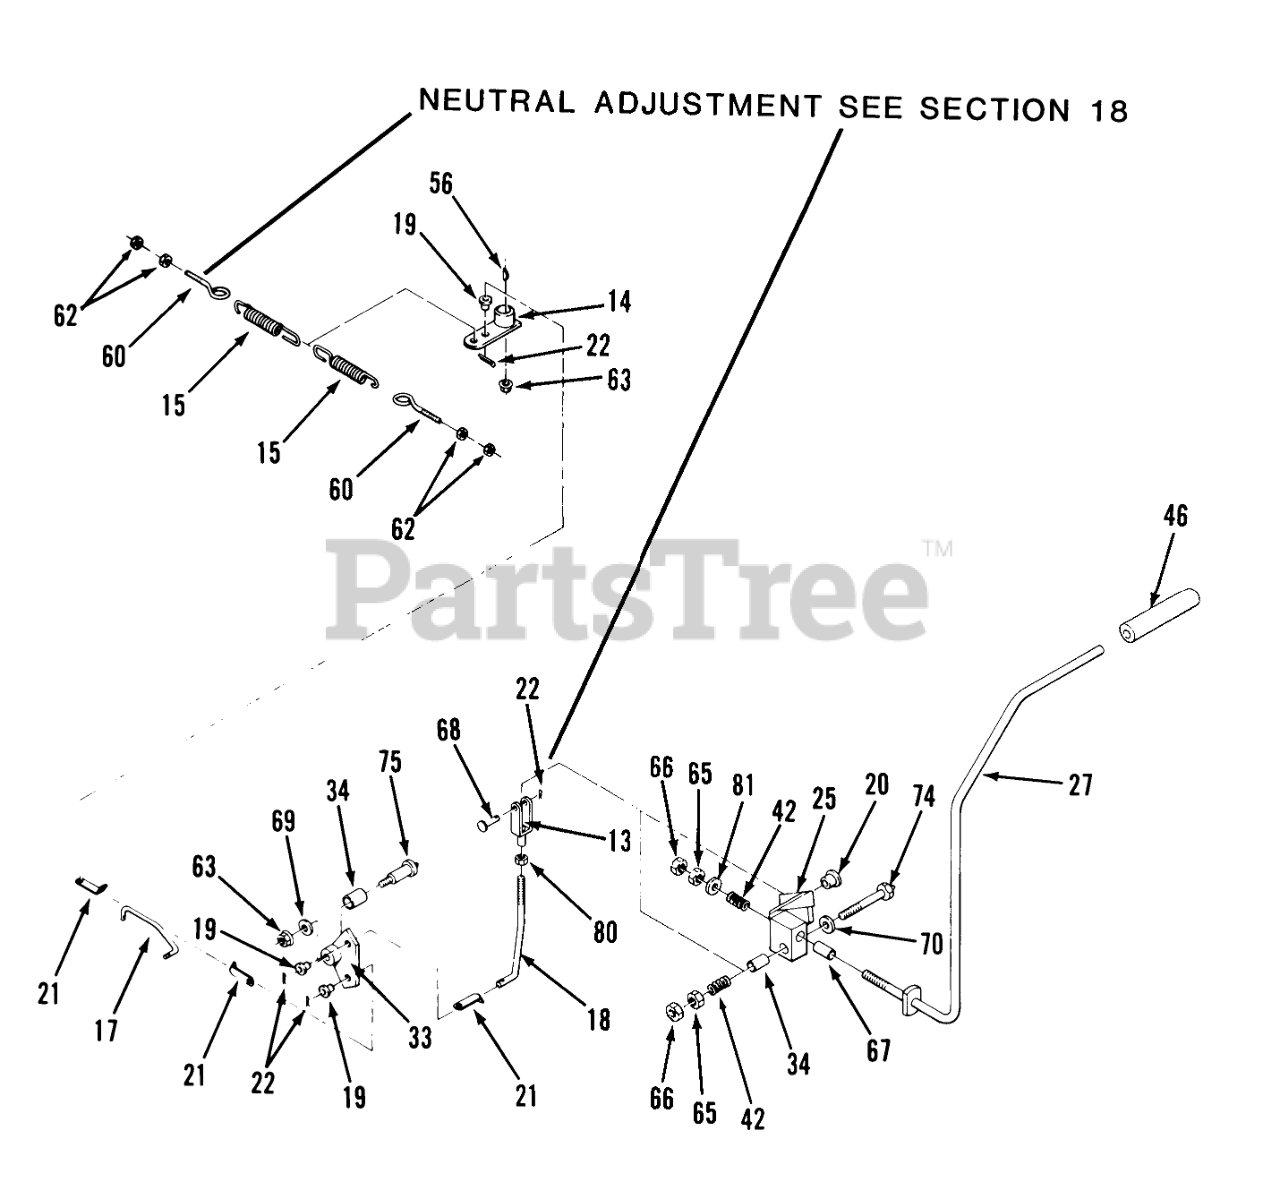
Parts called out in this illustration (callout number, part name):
13	CLEVIS
14	Hydro Control Arm
15	SPG-NEUTRAL 20217-35
17	Lower Drive Linkage RH
17	Lower Drive Linkage LH
18	LINKAGE-UPPER DRIVE
19	Nylon Bushing .296
20	Nylon Bushing 5/16
21	BACKING CLIP
22	HAIRPIN
25	STEERING LEVER LH
25	STEERING LEVER RH
27	Steering Lever LH
27	Steering Lever RH
33	PIVOT BLOCK
34	BUSHING
42	Spring
46	GRIP-HANDLE
56	KEY WOODR 1/8X1/2 DI
60	Eye Bolt
62	Nut
63	NUT
65	Eslok Nut
66	Jam Nut
67	Bronze Bushing
68	PIN CLEVIS 5/16X1
69	Washer
70	WASHER 7/16 SAE
74	Hex Bolt 1/2-13 x 4 1/2/w Grease Fitting
75	BOLT-SHOULDER B-116G
80	Nut-Lock
81	Washer
